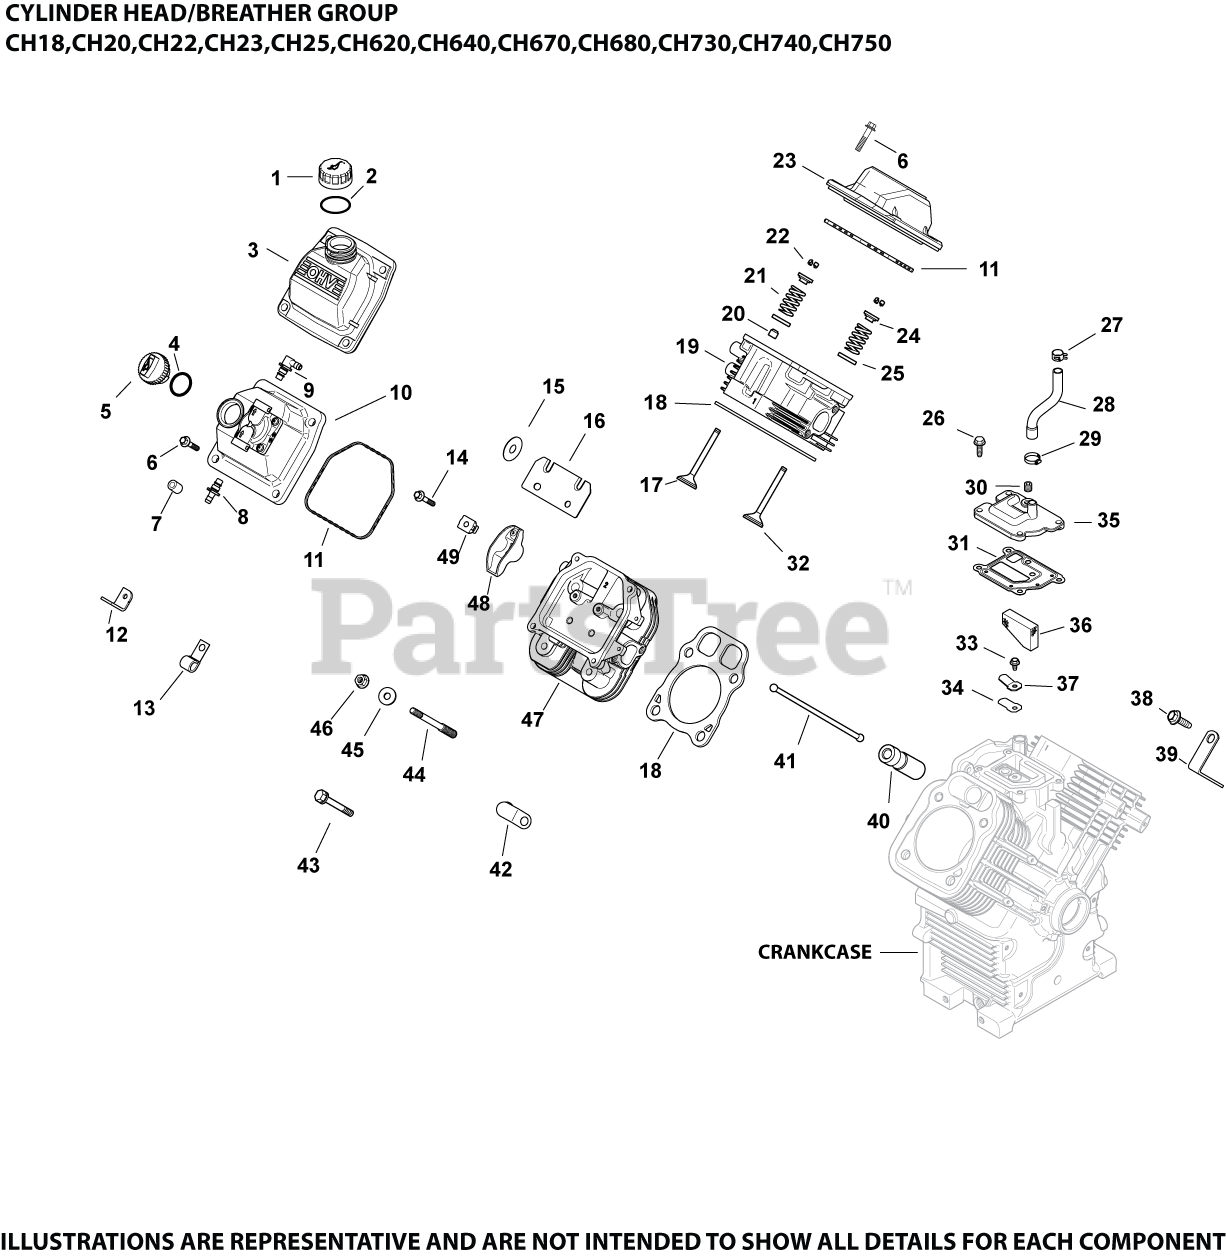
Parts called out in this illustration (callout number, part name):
4	O-RING-USE 24 153 32-S
5	CAP ASSY, OIL FILL (YELLOW)
6	SCREW, FLG M6X1.0X30
9	KIT, 90 DEG. FITTING
10	KIT, VALVE COVER-FUEL PUMP
11	O-RING (YELLOW), VALVE COVER
14	SCREW, FLG M6X1.0X34
17	VALVE, EXHAUST (STD) - USE 32 016 01-S
17	VALVE, EXHAUST (.25)
18	CYL HEAD GASKET KIT-USE 24 841 04-S
19	HEAD, ASSEM CYLINDER #1 -USE 24 318 107-
20	SEAL, VALVE STEM - (#2503214S)
21	SPRING, VALVE
22	KIT, RETAINER
23	KIT, VALVE COVER-PLAIN
24	RETAINER, VALVE SPRING - USE 25 173 28-S
25	RETAINER, SPRING
26	SCREW,FLG THD FRM M6X1.0X20-(#25086396S)
28	HOSE, BREATHER
29	CLAMP, HOSE (KM)-USE 25 237 31-S
30	PLUG, CTSK PIPE 1/8"
31	GASKET, BREATHER-USE 24 041 67-S
32	VALVE, INTAKE (STD)
32	VALVE, INTAKE (.25)
33	SCREW, FLG THD FRM M5X.8X10
34	REED, BREATHER
35	KIT, BREATHER ASSEMBLY
35	COVER, BREATHER -USE 24 033 01-S
36	FILTER, BREATHER
37	RETAINER, REED
39	STRAP, LIFTING-USE 25 445 03-S
40	LIFTER, HYDRAULIC VALVE-USE 25 351 10-S
41	ROD, PUSH
44	STUD, M8X1.25
45	WASHER, FLAT 8.6 MM
46	NUT, FLG M8X1.25
47	HEAD, SERVICE ASSY CYL #2-USE 24 318 114
48	ARM, ROCKER
49	PIVOT, ROCKER ARM
